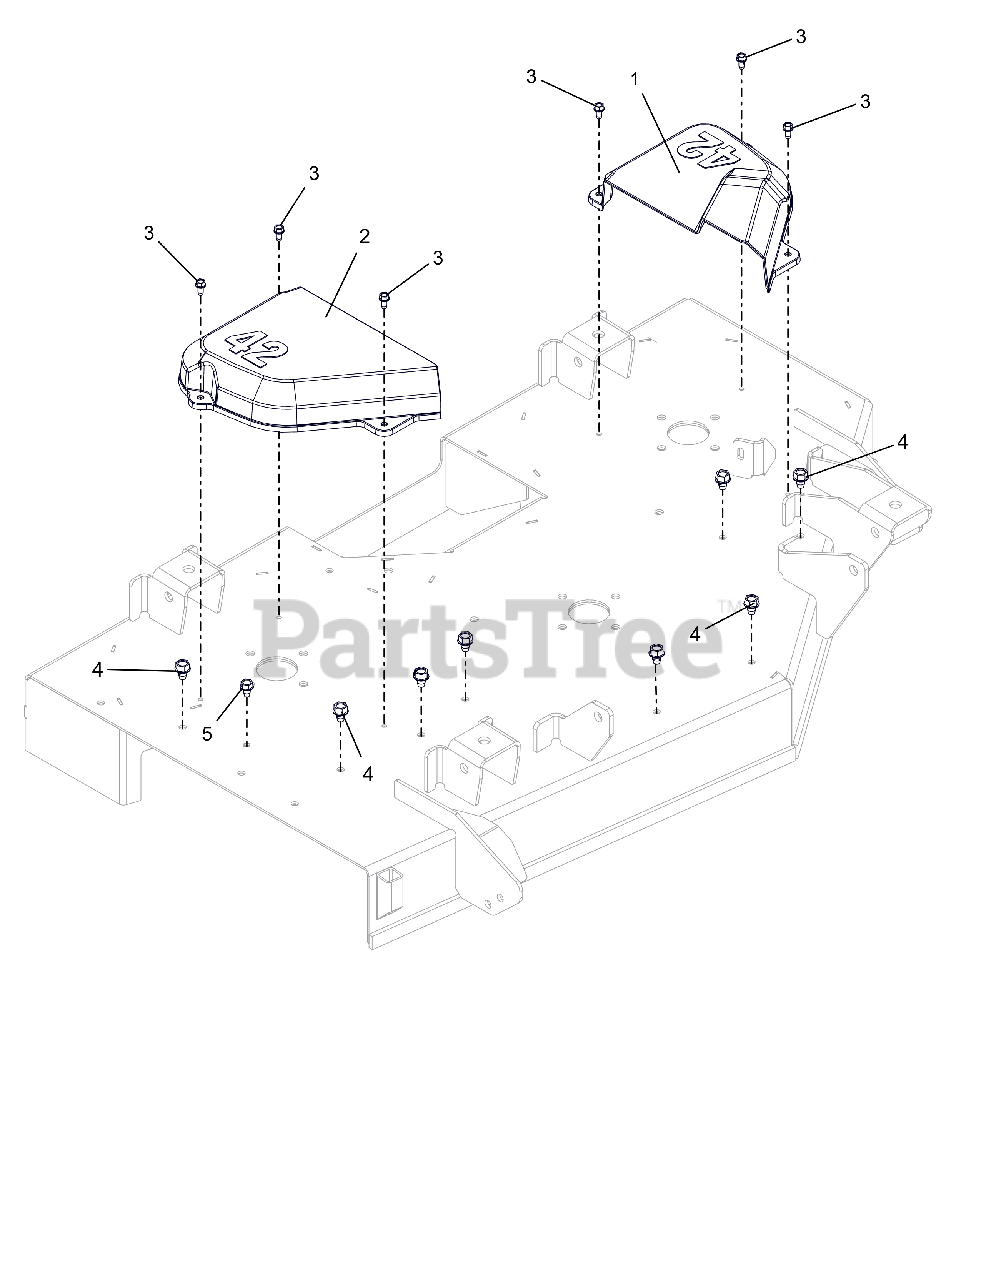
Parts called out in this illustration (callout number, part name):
1	COVER, BELT 42" LH
2	COVER, BELT 42" RH
3	SCR-TAP .25-20X.50 HWH ZCC
4	SCR,TAP .375-16X.50 HWH TR ZCC
5	SCR,TAP .312-18X.50 HWH TR ZCC
